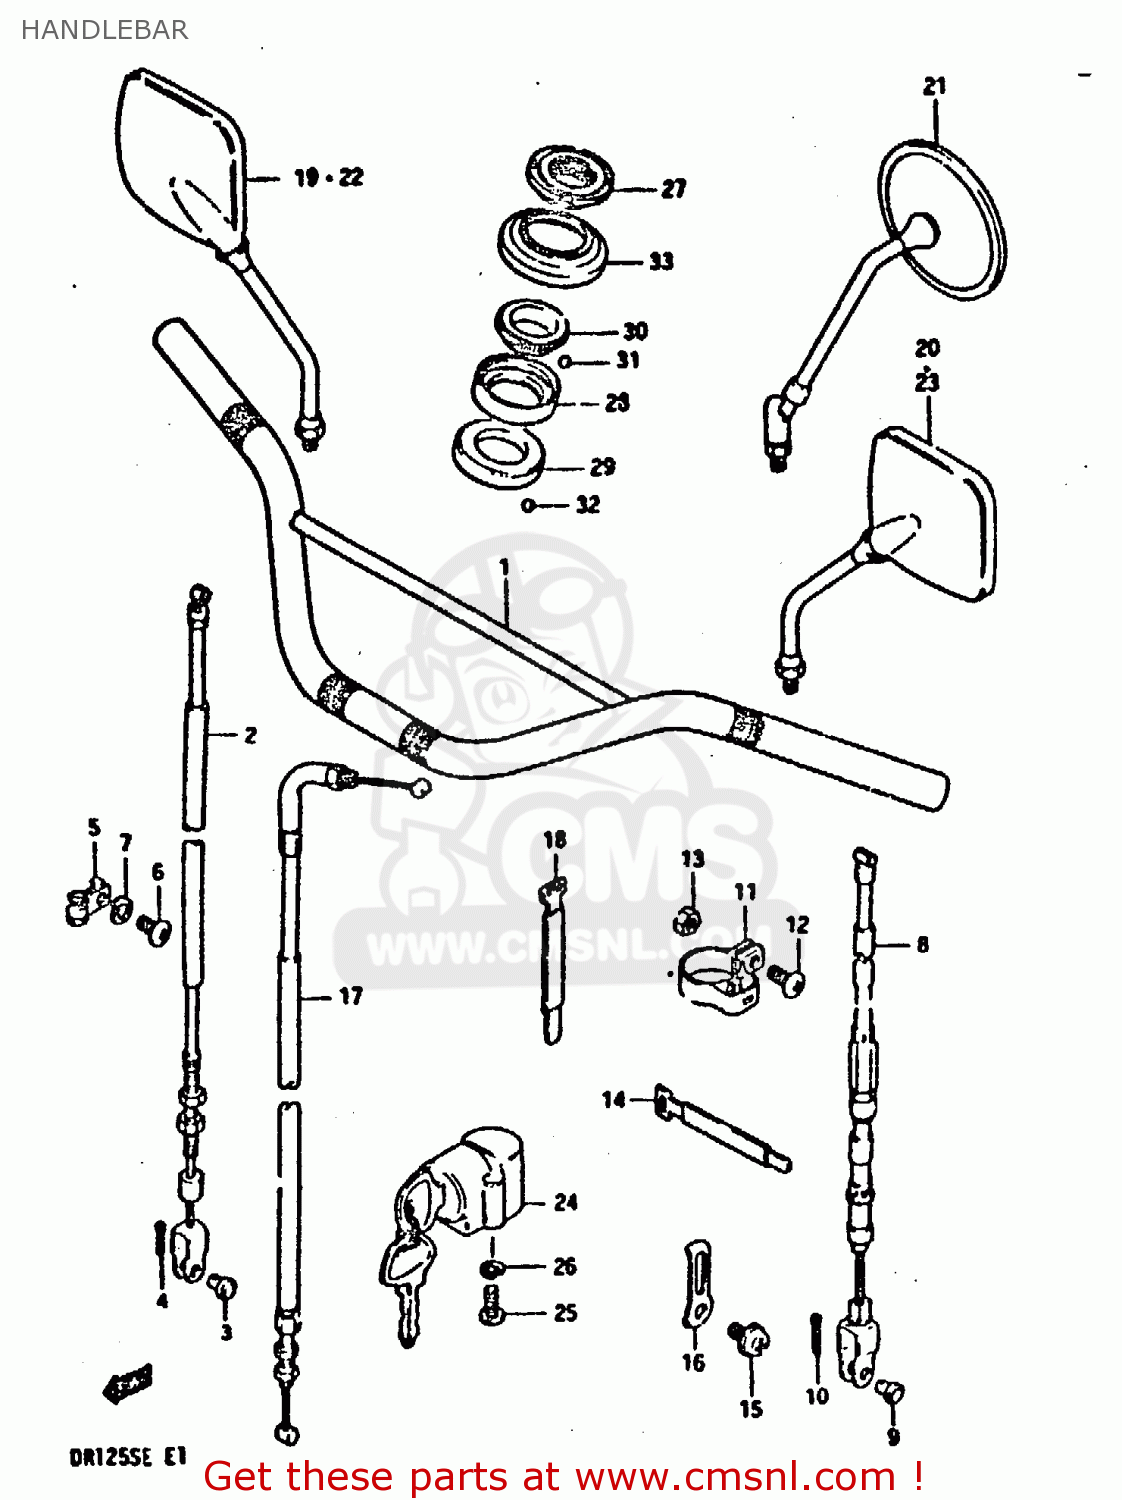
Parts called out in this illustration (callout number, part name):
1	HANDLE BAR
2	CABLE,FRONT BRAKE
3	PIN(L:17.5)
4	PIN
5	CLAMP,FR BRAKE CABLE
6	SCREW 6X12
7	LOCK WASHER
8	CABLE ASSY,CLUTCH
9	PIN(L:15)
10	PIN
11	CLAMP,CABLE
12	SCREW
13	NUT
14	CLAMP
15	SCREW
16	CLAMP,CABLE
17	CABLE ASSY,THROTTLE
18	CLAMP
19	MIRROR ASSEMBLY,REAR VIEW
20	MIRROR ASSEMBLY,LEFT
21	MIRROR ASSY, REAR VIEW
22	MIRROR, REAR VIEW RH
23	MIRROR, REAR VIEW LH
24	LOCK ASSY,STEERING
25	SCREW
26	LOCK WASHER
27	NUT,STEERING STEM(25X44X10)
28	RACE,STEERING INNER UPR
29	LACE,STEERING INNER LWR
30	RACE,STEERING OUTER UPR
31	BALL
32	BALL
33	DUST SEAL,STEERING UPR
